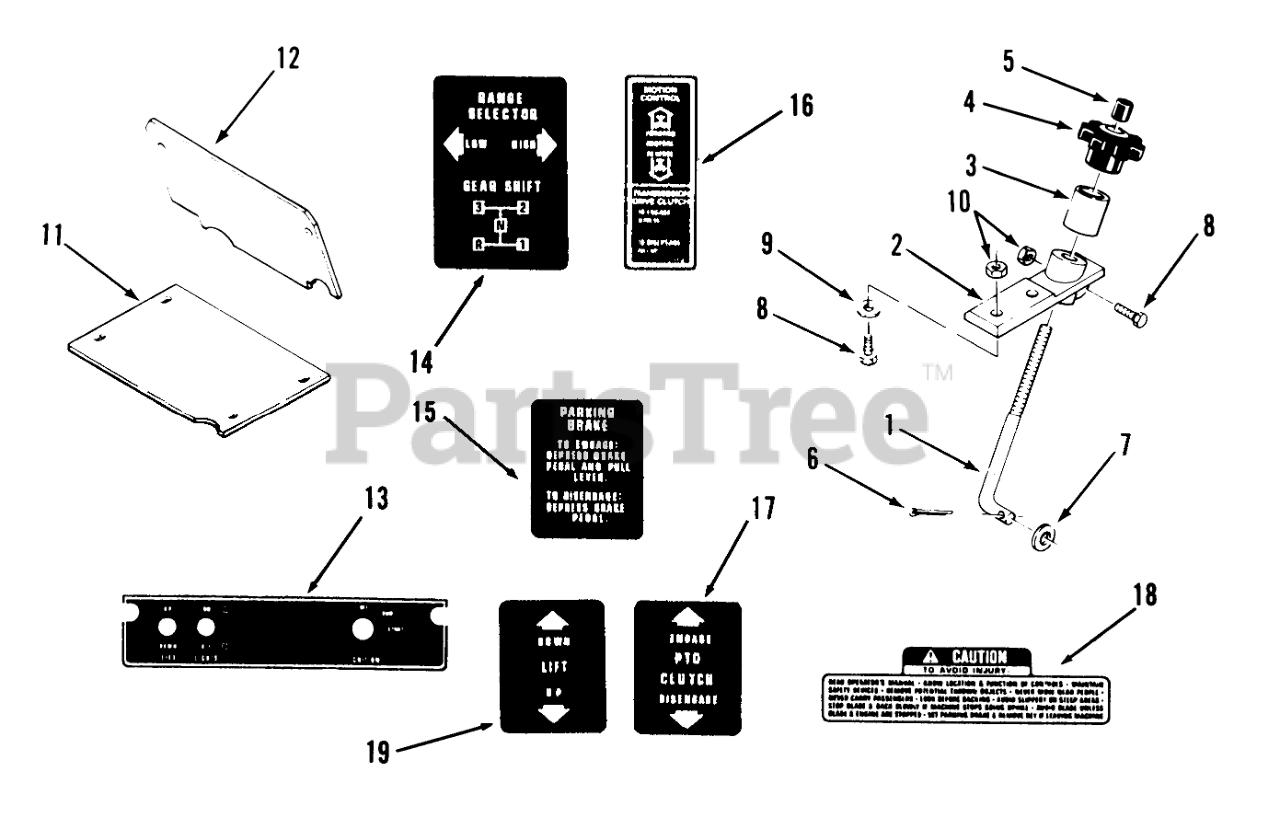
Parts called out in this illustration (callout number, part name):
1	ROD-HEIGHT CONTROL
2	Casting
3	Sleeve
4	KNOB-LIFT CONTROL
5	CAP-ROD, PLUNGER
6	Pop Rivet
7	WASHER -4
8	Bolt
9	WASHER 5/16 SAE
10	Nut
11	Plate-Shift Cover
12	Plate-Hoodstand w/o Instrument locations
13	DECAL BACK PLATE
14	DECAL-SHIFT PATTERN
15	DECAL-PARKING, BRAKE
16	DECAL SPD CONTROL
17	DECAL PTO
18	DECAL CAUTION
19	DECAL LIFT
